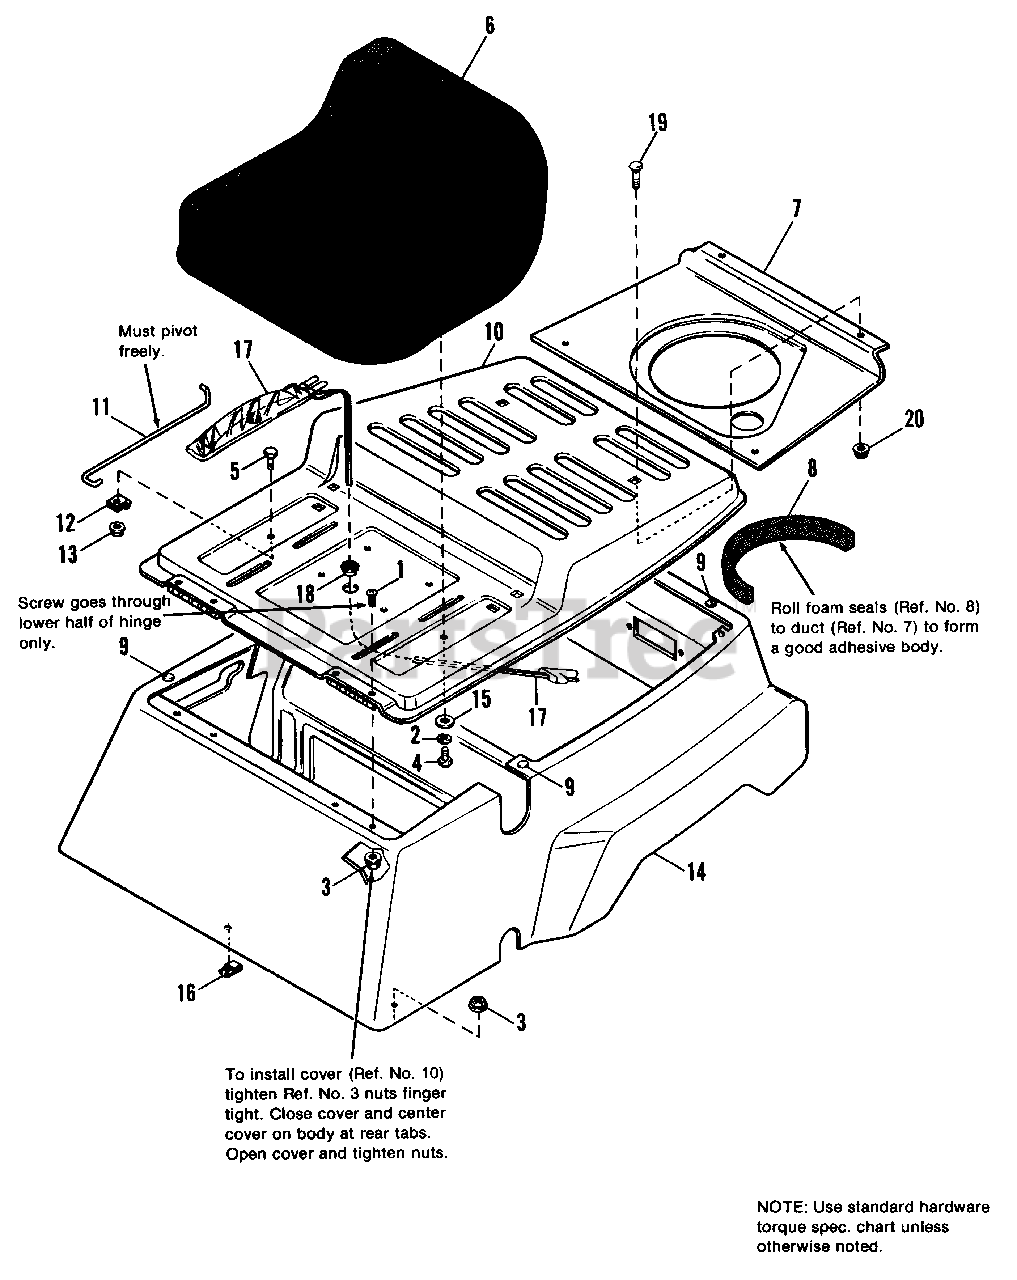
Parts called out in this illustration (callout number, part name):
1	SCREW, Truss, Phil. Hd., 5/16-18 x 7/16
2	LOCKWASHER, 5/16
3	LOCKNUT, Flange, Whiz, 5/16-16
4	CAPSCREW, 5/16-18 x 5/8
5	CAPSCREW, Hex, 1/4-20 x 1/2
7	DUCT, Inlet
8	SEAL, Foam (Mfg. No. 1691106 Only)
8	SEAL, Foam (Mfg. No. 1691108 Only)
9	PLUG, Bumper
10	COVER ASSY.
11	ROD, Cover Support
13	LOCKNUT, Flange, 1/4-20
14	BODY ASSY.
15	WASHER, Plain, 5/16
16	NUT, Speed, 5/16-18
17	SWITCH, Seat, Operator Present
18	BUSHING, Universal
19	BOLT, Carriage
20	LOCKNUT, Pal, #10-24
